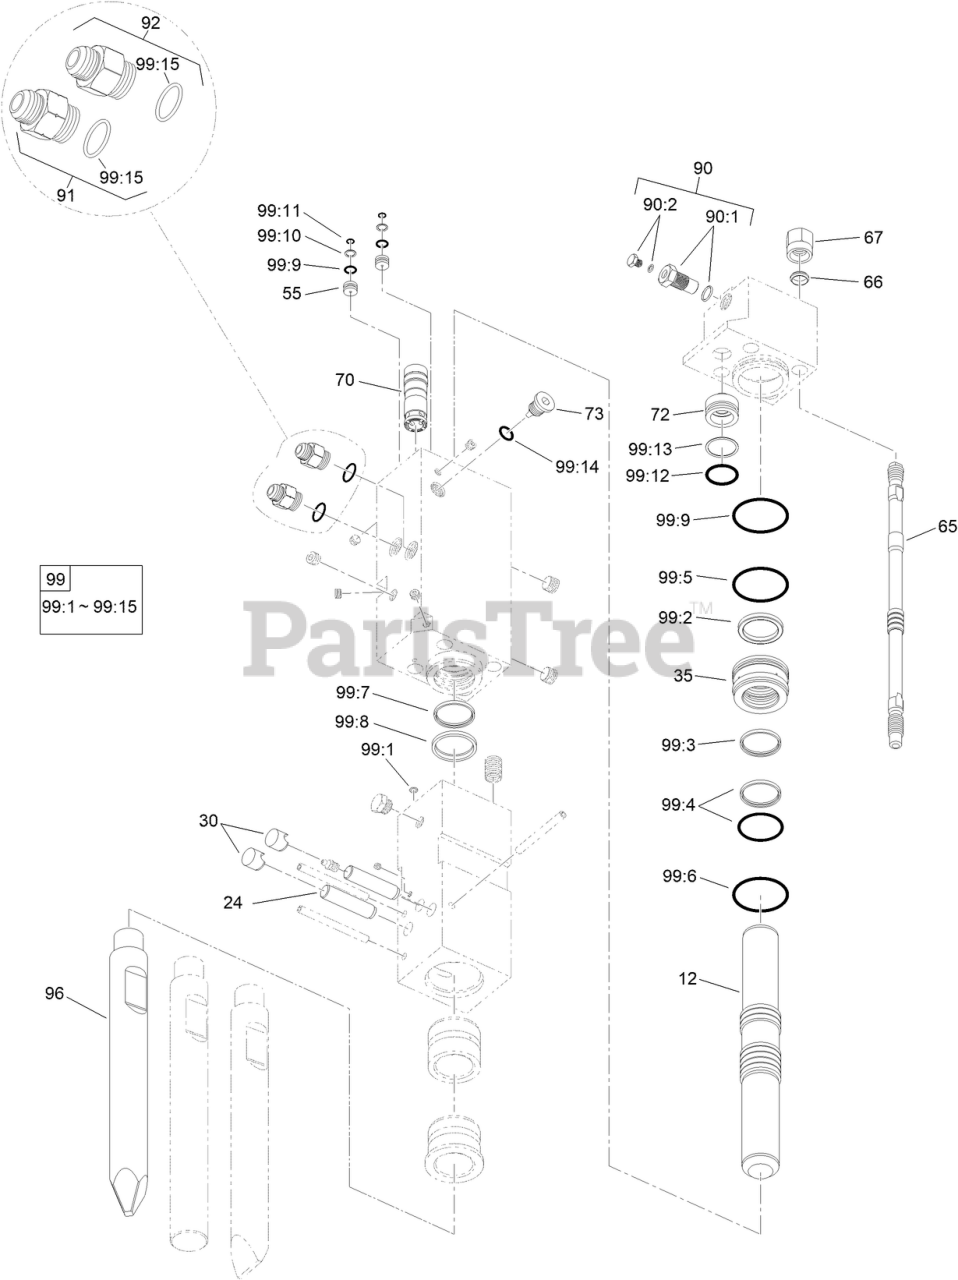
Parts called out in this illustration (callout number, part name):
12	PISTON
24	PIN - RETAINER
30	PLUG - RETAINER, PIN
35	BUSHING - PACKING
55	PLUG - CYLINDER
65	BOLT - SIDE
66	RING - BOLT, SIDE
67	NUT - BOLT, SIDE
70	VALVE - CONTROL
72	CAP - VALVE, CONTROL
73	PLUG - CHOKE
90	KIT - VALVE, GAS
90:1	GAS VALVE BODY CP
90:2	GAS VALVE PLUG CP
91	ADAPTER - HOSE, IN
92	ADAPTER - HOSE, OUT
96	CHISEL - POINT
99	KIT - SEAL
99:1	O-RING
99:2	GAS SEAL
99:3	OIL SEAL
99:4	SLIDE RING S
99:5	O-RING
99:6	O-RING
99:7	OIL SEAL
99:8	Dust Seal
99:9	O-RING
99:10	O-RING
99:11	Back Up Ring
99:12	O-RING
99:13	Back Up Ring
99:14	O-RING
99:15	O-RING
